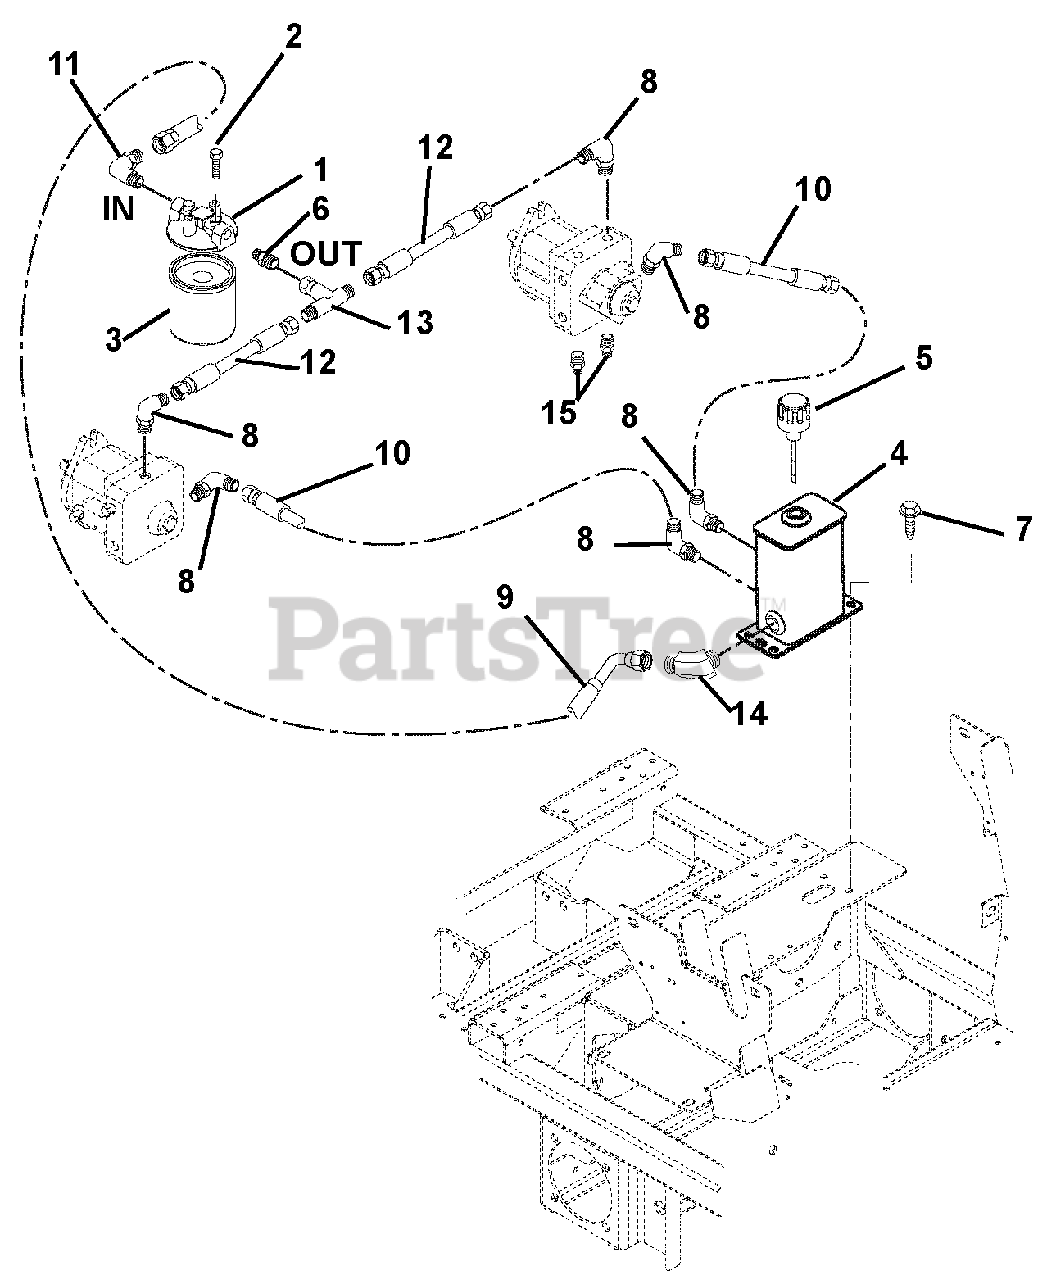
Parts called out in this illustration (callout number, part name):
1	Head, Filter (SN 000101 - 002600)
2	Bolt-Hex .25-20 x .50 Grade 5 Epoxy
3	Filter Element
4	Body, Hydraulic Tank (SN 000101 – 003999)
5	Breather, Dipstick
6	Fitting, Hydraulic, Straight (SN 000101 - 002600)
7	Screw-Tapping .38-16 x .75 Hex Washer Head
8	Fitting, Hydraulic, 90 Degree Elbow
9	Hose-Hydraulic Valve to Tank
10	Hose, Hydraulic, 10-inch
11	Fitting, Hydraulic, 90 Degree Elbow (SN 000101 - 002600)
12	Hose, Hydraulic .50, 5-Inch
13	Fitting, Hydraulic Tee
14	Fitting, Hydraulic .45 Degree Elbow (SN 000101 – 003999)
15	Fitting, Hydraulic (4 F5OLO)
